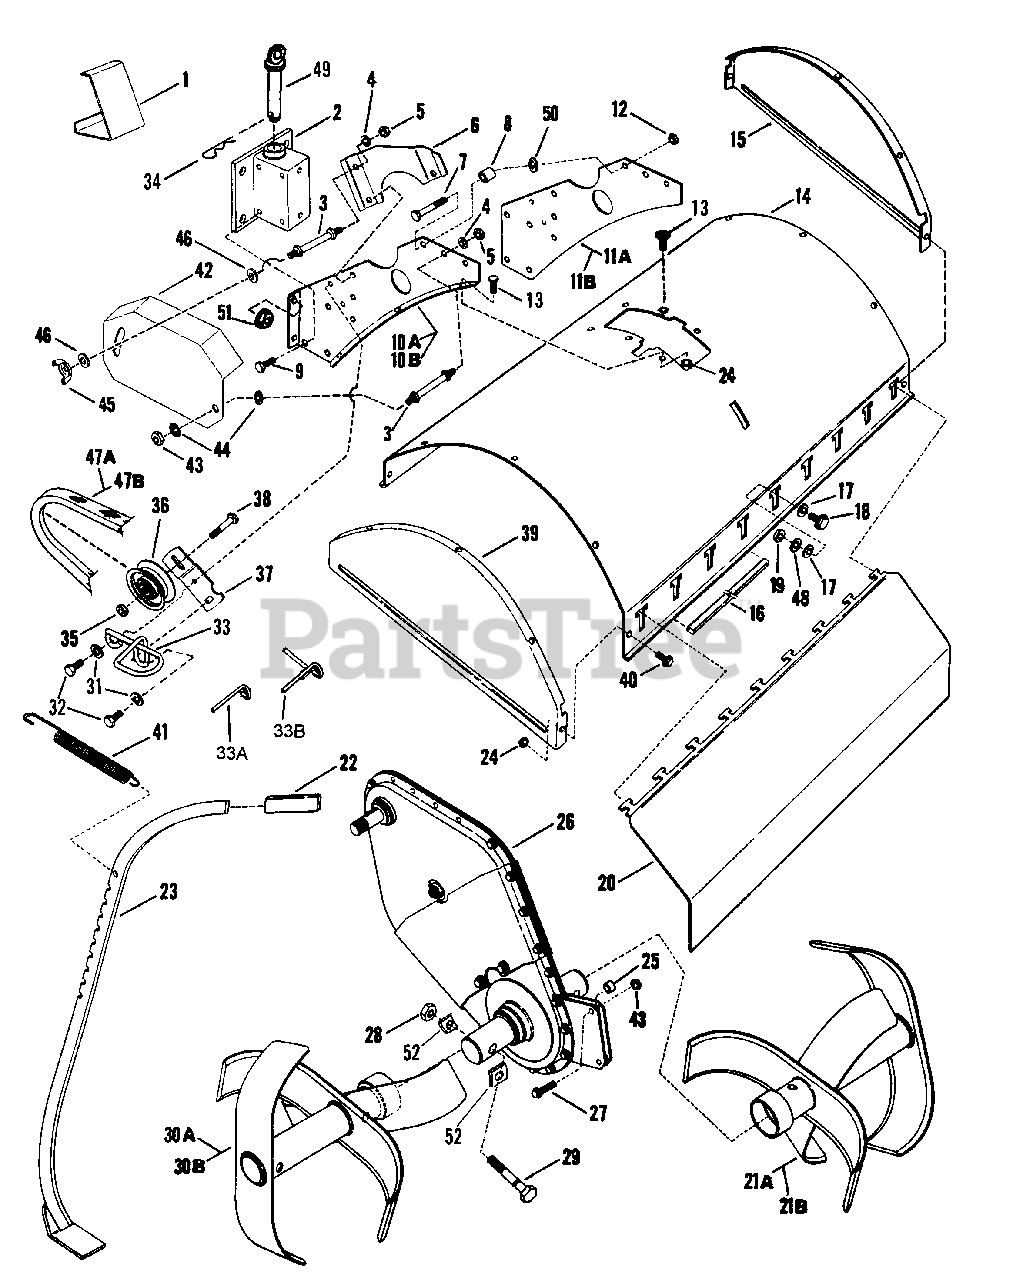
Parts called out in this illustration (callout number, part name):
1	(NLA) SPACER
2	BRACKET, Mounting
3	(NLA) STUD
4	WASHER, 5/16 Split Lock
5	NUT, 5/16-18 Hex
6	(NLA) SHIELD
7	SCREW, 5/16-24 x 2-1/2" Hex Head Cap, Grade 8
8	SPACER
9	SCREW, 3/8-16 x 1/2" Hex Washer Self-Tap
10A	BRACKET, Mounting L.H. (8HP)
10B	BRACKET, Mounting L.H. (5HP)
11A	BRACKET, Mounting R.H. (8HP)
11B	BRACKET, Mounting R.H. (5HP)
12	NUT, 5/16-24 Hex Lock, Grade C
13	BOLT, 5/16-18 x 5/8" Short Neck Carriage, Grade 5
14	COVER, Tine
15	PLATE, Right Side
16	(NLA) MOLDING, Trim
17	WASHER, 3/8" SAE Flat
18	SCREW, 3/8-16 x 3/4" Hex Head Cap, Grade 5
19	NUT, 3/8-16 Hex
20	GUARD, Splash
21A	TINE STRUCTURE, R.H. (8HP)
21B	TINE STRUCTURE, R.H. (5HP)
22	GRIP, Depth Bar
23	DEPTH BAR STRUCTURE
24	NUT, 5/16-18 Hex Flange lock
25	SPACER
26	ASSEMBLY, Chain Case
27	SCREW, 5/16-18 x 1" Hex Head Cap, Grade 2
28	NUT, 3/8-24 Hex Center Lock
29	BOLT, 3/8-24 x 2-1/4" Shear
30A	TINE STRUCTURE, L.H. (8HP)
30B	TINE STRUCTURE, L.H. (5HP)
31	WASHER, 5/16 SAE Flat
32	SCREW, 5/16-18 x 1" Hex Washer Self-Tap
33	FINGER, Belt
33A	FINGER, Belt R/B 14875
33B	FINGER, Belt R/B 14875
34	PIN, Hair
35	NUT, 5/16-24 Hex Center Lock
36	IDLER
37	ARM, Idler
38	BOLT, 5/16-18 x 1-3/4" Square Neck Carriage, Grade 5
39	PLATE, L.H.
40	BOLT, 5/16-18 x 1/2" Short Neck Carriage, Grade 5
41	SPRING
42	COVER, Belt
43	NUT, 5/16-18 Hex Center Lock
44	WASHER, Seal
45	NUT, 5/16-18 Wing Lock
46	WASHER, 5/16 SAE Flat
47A	V-BELT, 4 L x 62.38" Effective Length - Kevlar
47B	V-BELT, 4 L x 62.0" Effective Length - Kevlar
48	WASHER, 3/8 Split Lock
49	CLEVIS PIN, 3/4 X 6-1/16, ZP
50	RETAINER, 5/16" Bolt
51	NUT, 3/8-16 Hex Flange Lock (5HP only)
52	WASHER, Curved (now welded to Tine)
